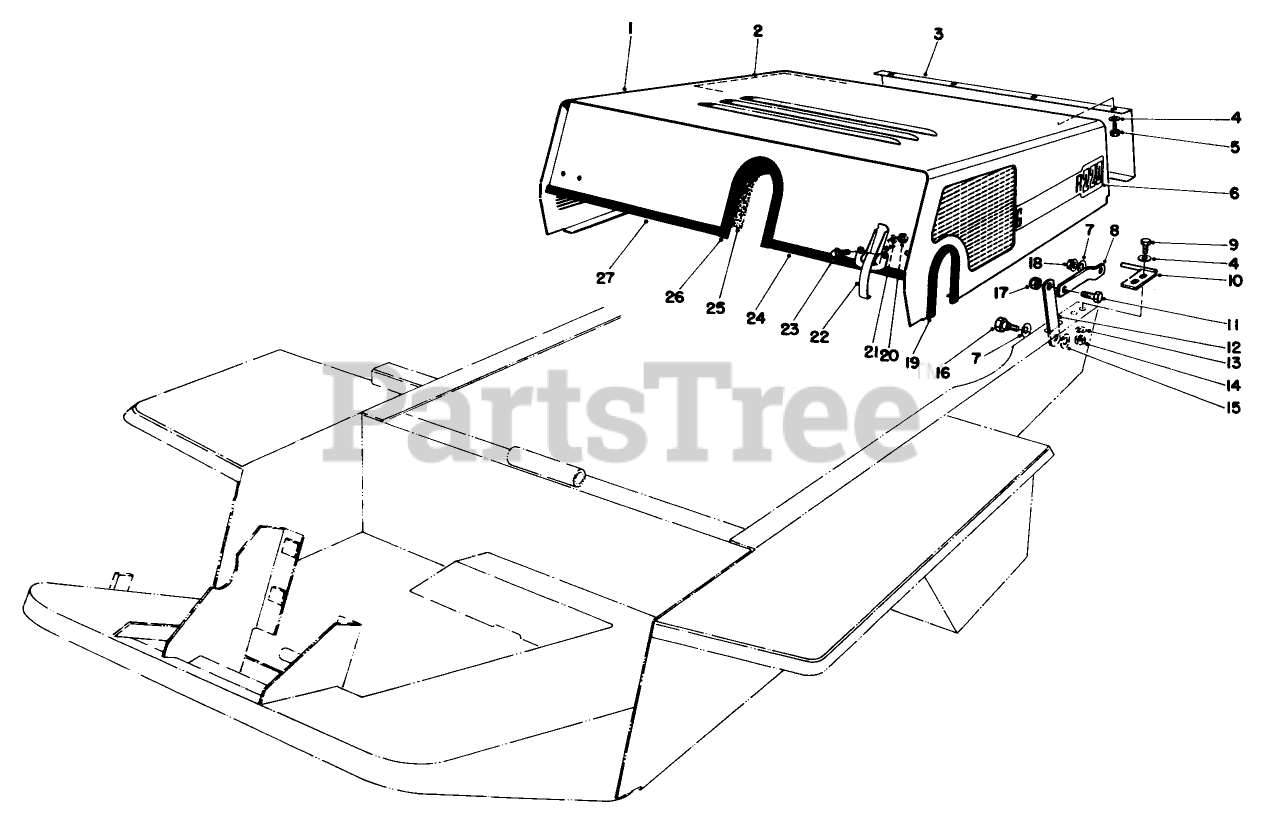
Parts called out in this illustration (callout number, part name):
2	REAR HOOD FOAM STRIP
4	WASHER-FLAT
7	WASHER-SPRING
9	SCREW-HH
13	WASHER-LOCK
14	NUT-HEX
15	WASHER-FLAT
16	SCREW-SHOULDER
17	NUT-HEX
18	NUT-HF
20	NUT-HEX
21	WASHER-LOCK
22	CLAMP-SLOTTED
23	SCREW-SHWH
26	HOOD TRIM
27	TRIM-HOOD
